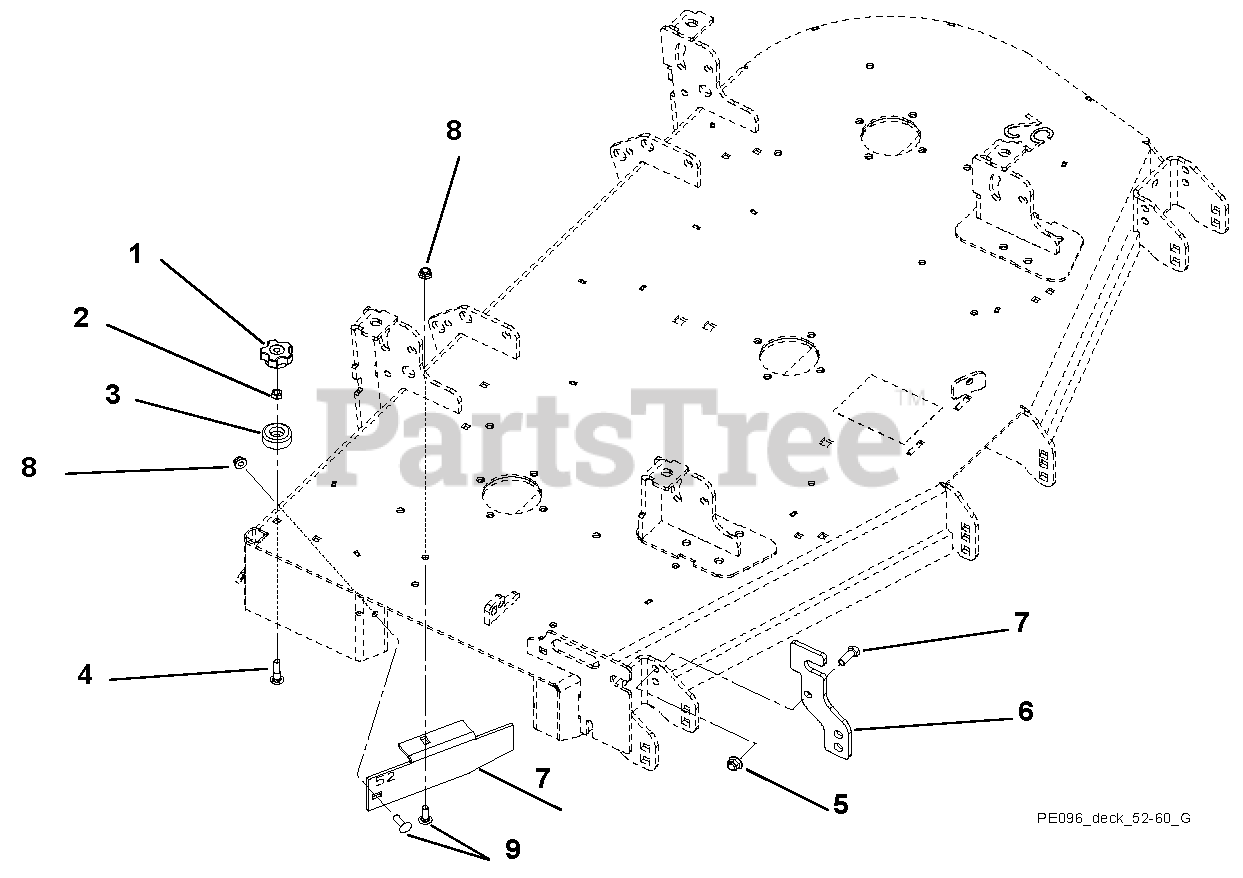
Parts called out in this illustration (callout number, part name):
1	Knob, Clamping, .312-18 Nyloc
2	Nut, Locking Center .31-18
3	Bumper, Recessed 1.50 x .63 w/.31 Thru Hole
4	Bolt, Round Head Square Neck .31-18 x 1.50
5	Nut, .38-16 Nyloc Flange
6	Chute Storage Bracket
7	Bolt, Hex .38-16 x 1.00
8	Nut, Locking Nyloc Flange .31-18
9	Bolt, Round Head Square Neck .31-18 x 1.00
10	Discharge Baffle (991080, 096)
